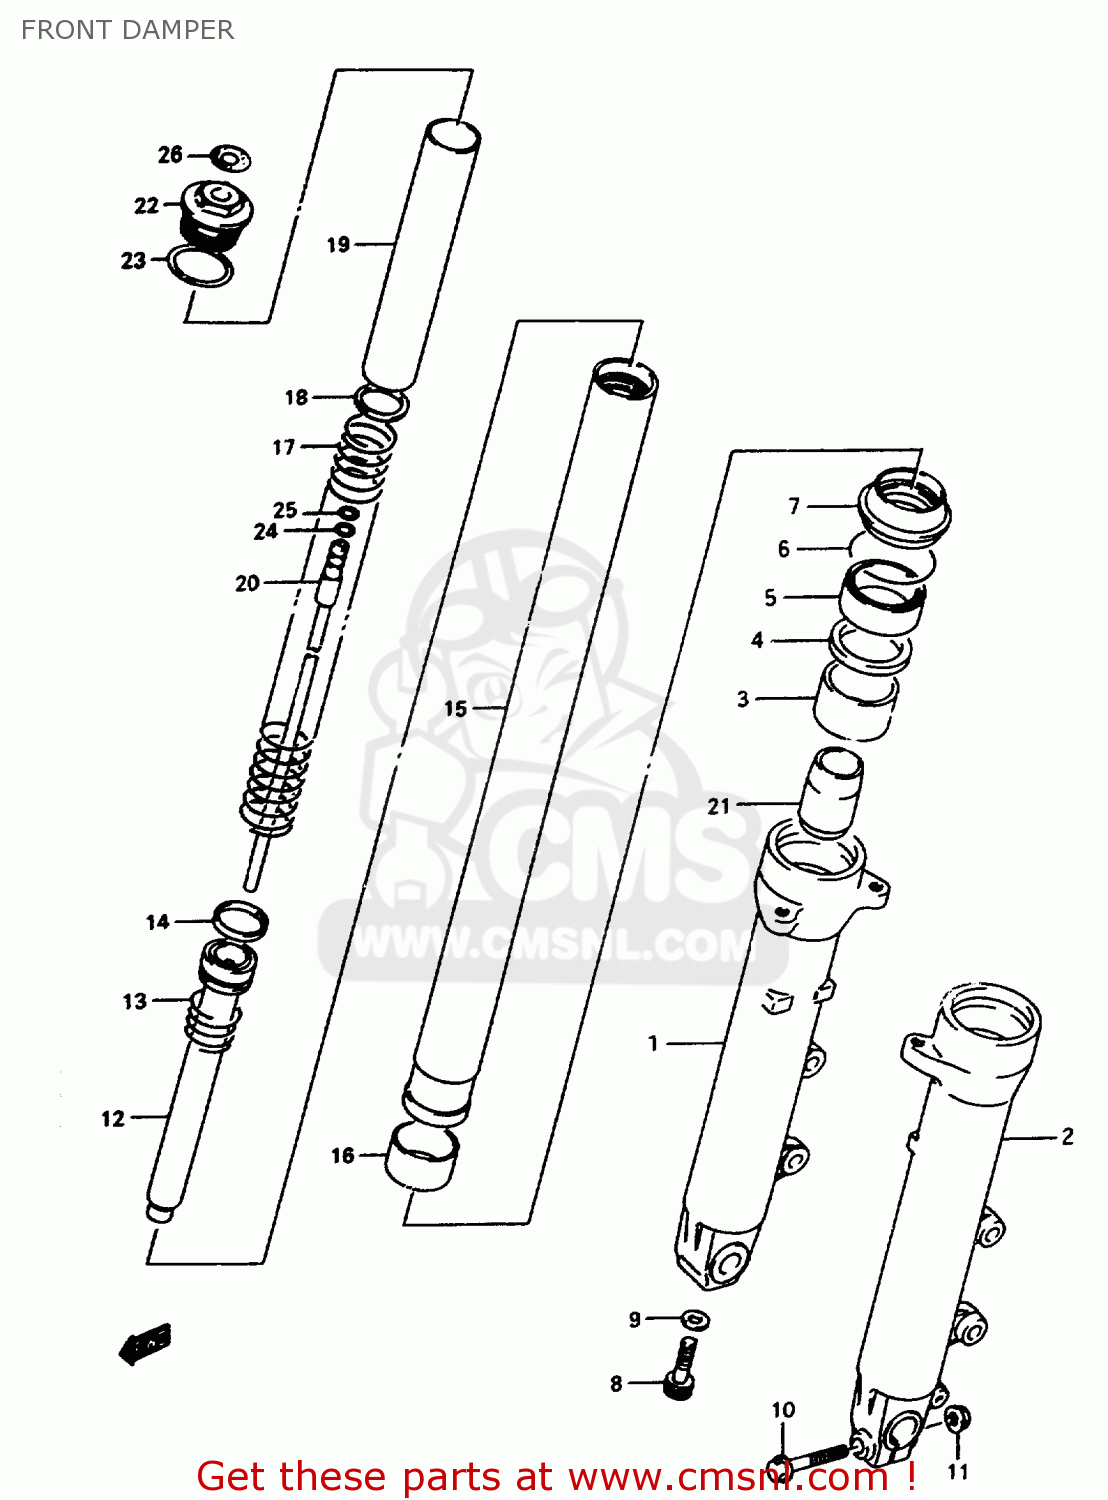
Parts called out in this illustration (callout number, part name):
1	TUBE,OUTER,RIGHT
2	TUBE,OUTER,L
3	BUSH,GUIDE
4	SPACER,SEAL
5	SEAL,OIL
6	CIRCLIP,FORK OIL SEAL
7	SEAL,DUST
8	BOLT(8X27)
9	GASKET (NAS)
10	BOLT
11	NUT
12	PIPE,SEAT UNDER
13	SPRING,REBOUND
14	RING,PISTON
15	TUBE,INNER
16	BUSH,SLIDE
17	SPRING,FRONT
18	JOINT,SPRING
19	SPACER,SPRING
20	ROD,INNER
21	PIECE,OIL LOCK
22	BOLT,FORK
23	O RING
24	O RING(D:1.9,ID:5.7)
25	RING,STOPPER(ID:6.1,D:0.6)
26	LABEL,S-H
